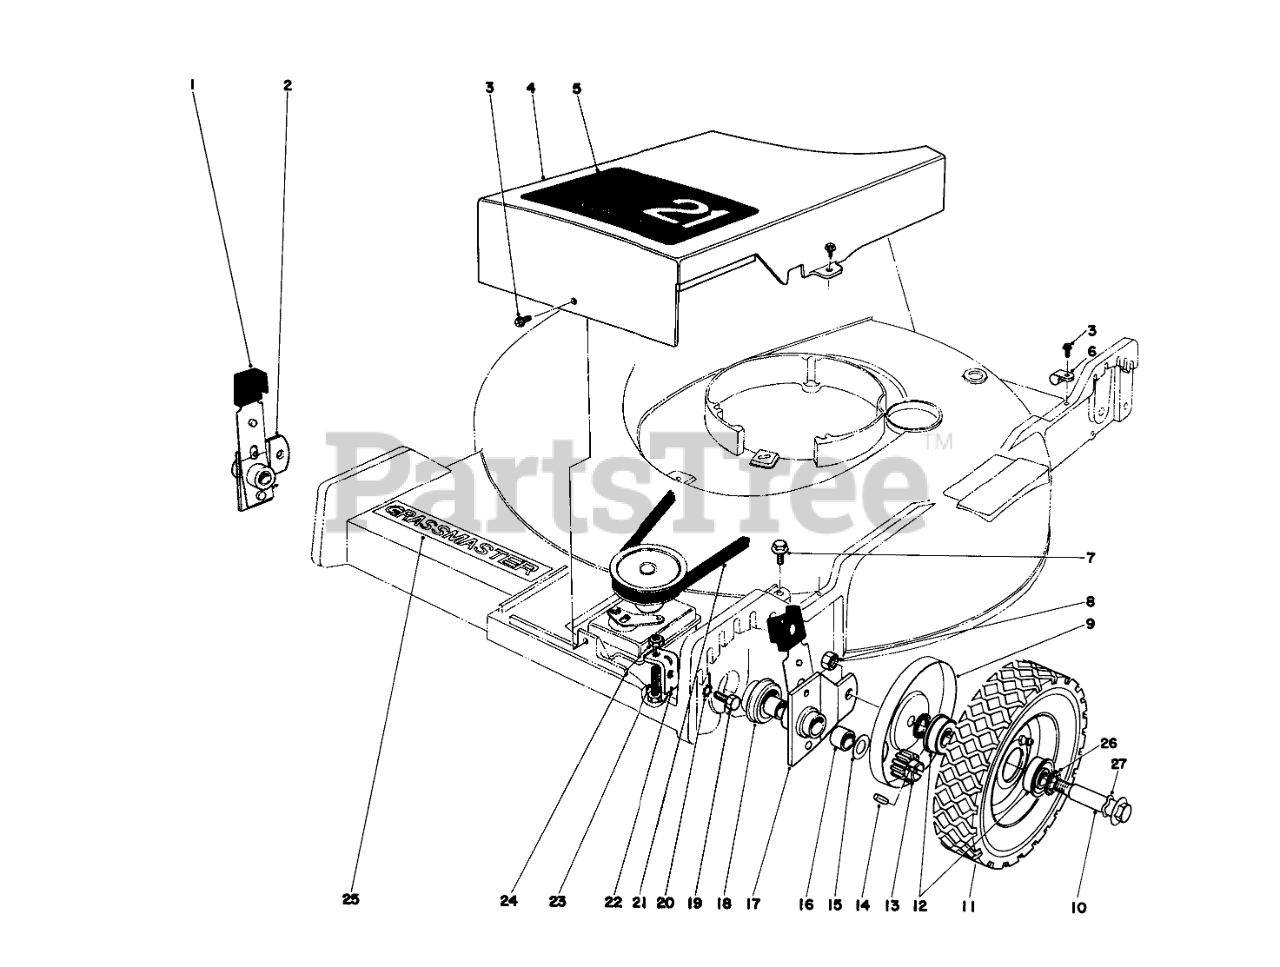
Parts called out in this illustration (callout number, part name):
1	KNOB-ARM
2	Pivot Arm (Incl. Ref. #16)
3	SCREW
4	Belt Cover
5	Decal Belt Cover
6	CLAMP-NYLON
7	SCREW-HWHTF
8	Nut
9	WHEEL COVER
10	WHEEL BOLT
11	Wheel & Tire Assembly Front (Incl. Ref. #12)
12	BEARING-BALL
13	Pinion
14	PIN-GROOVED
15	WASHER-THRUST
16	BUSHING
17	Pivot Arm (Incl. Ref. #16)
18	End Cap
19	SCREW-HH
20	WASHER-LOCK
21	V-BELT
22	Bracket-Gear Box
23	SCREW
24	NUT-LOCK
25	Decal Grassmaster
26	FELT WASHER
27	SPRING WASHER
